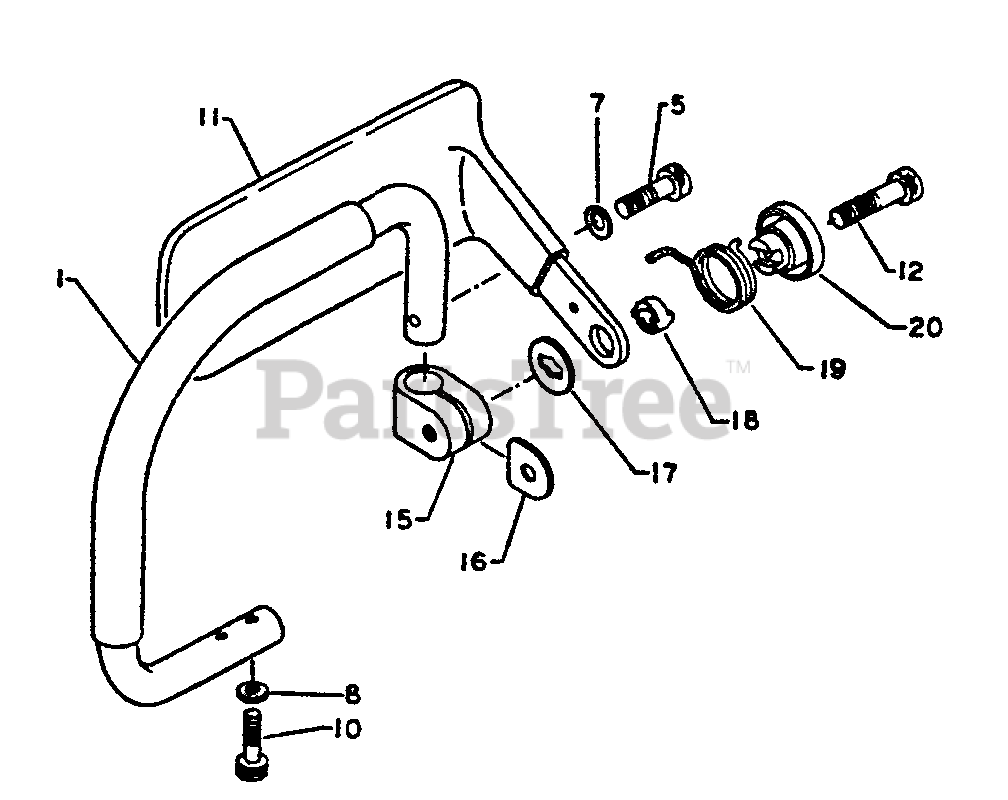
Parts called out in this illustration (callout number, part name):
1	HANDLE - FRONT
5	SCREW - 5X20
7	WASHER - 5
8	WASHER - 4
10	SCREW - 4X18
10	HAND GUARD ASSY
12	SCREW - 5X30
15	HOLDER
17	WASHER
20	RETAINER
